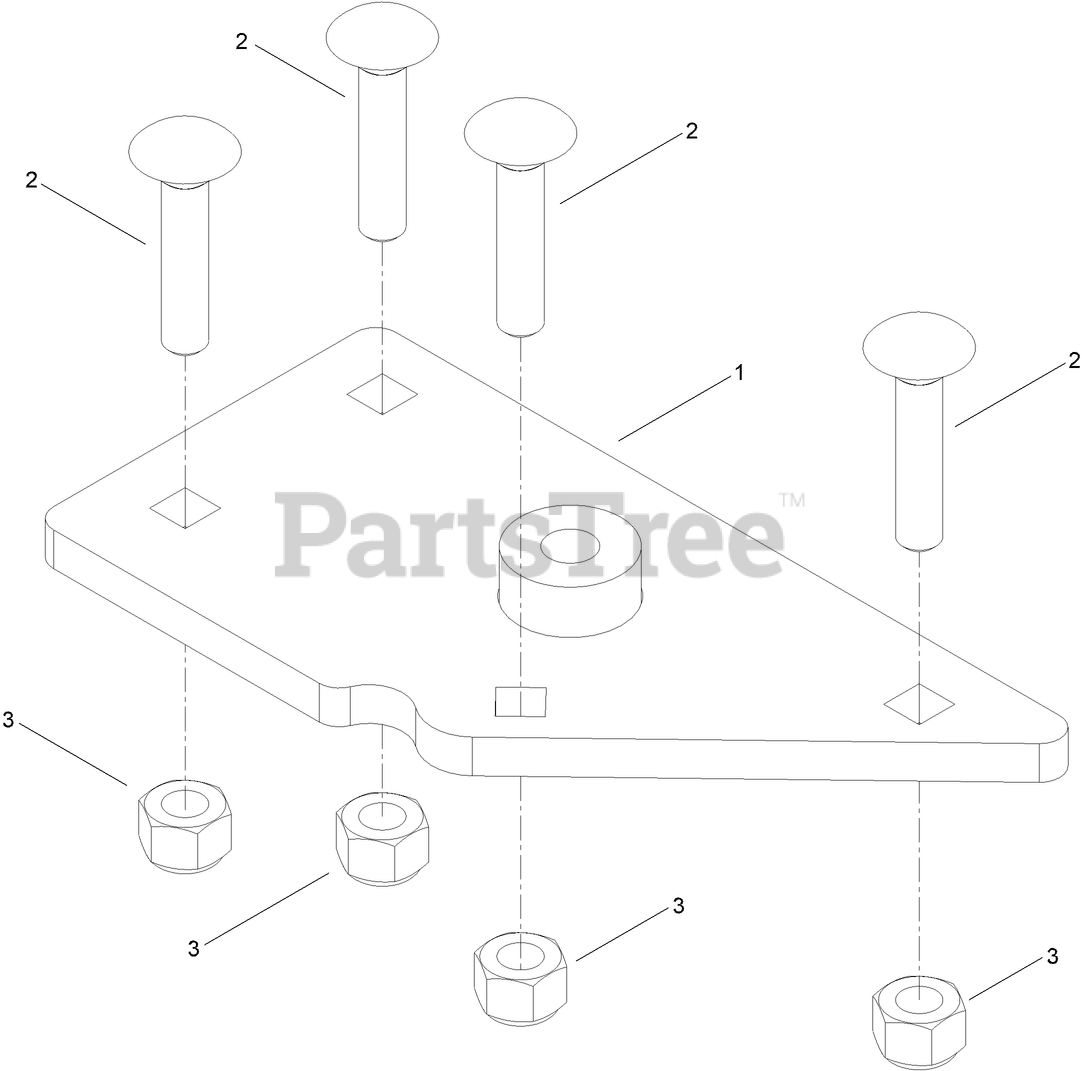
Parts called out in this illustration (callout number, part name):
1	PLATE-FRAME, ASM
2	SCREW-CARR
3	NUT-LOCK, NI
